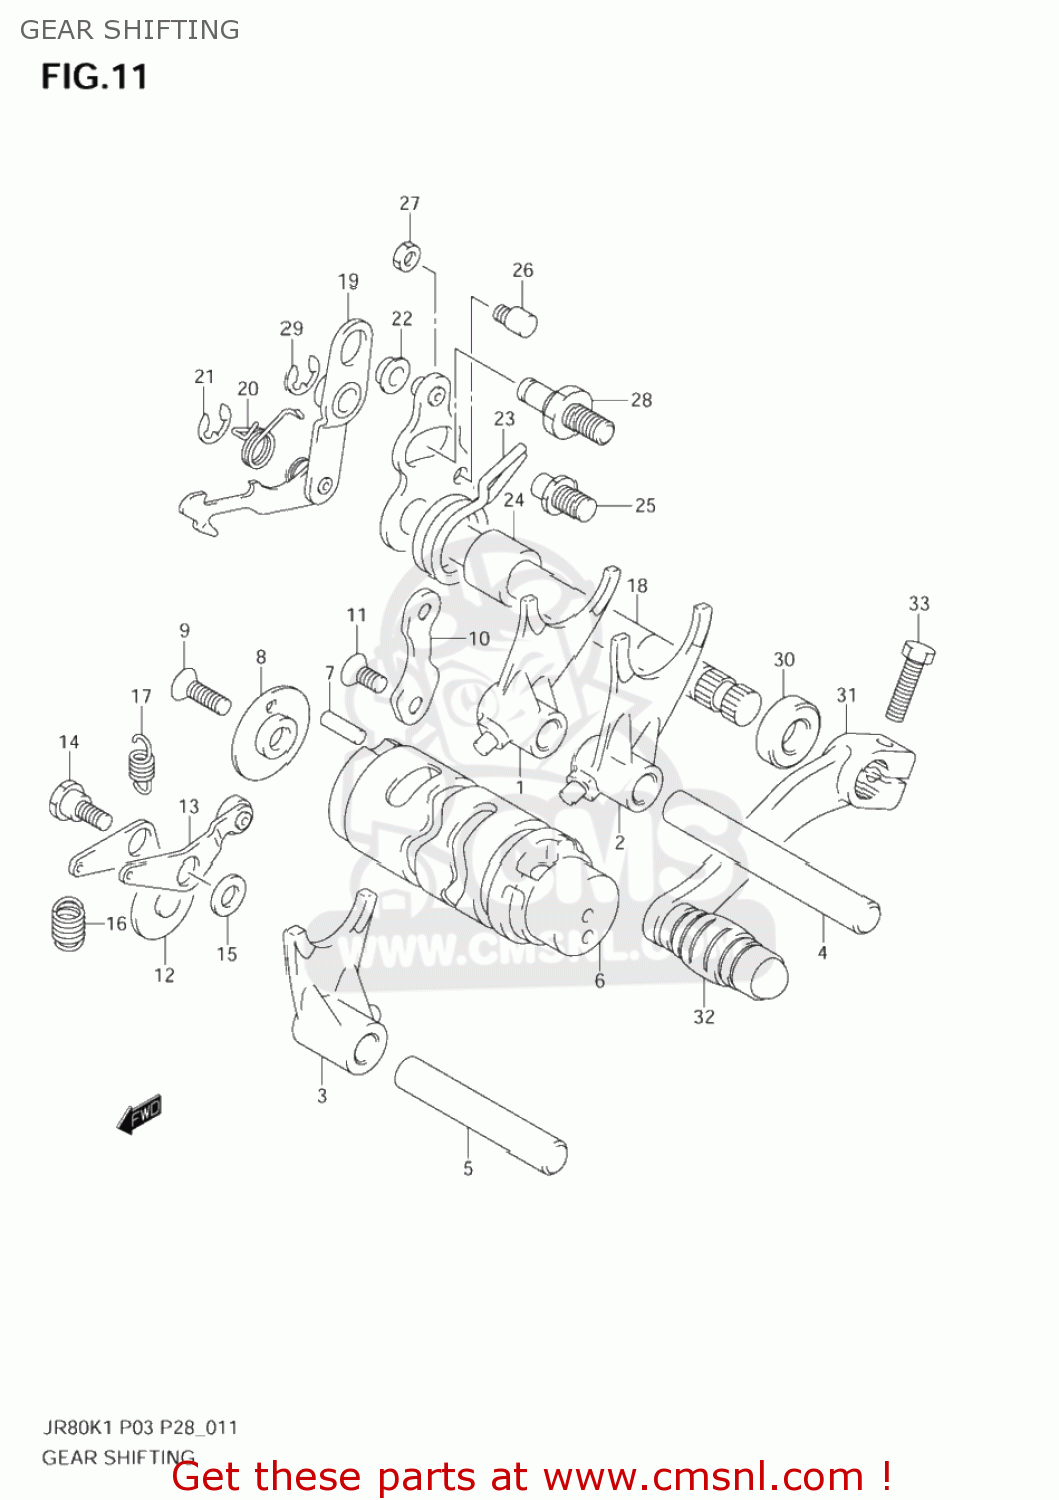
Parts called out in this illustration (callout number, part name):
1	FORK,GEAR SHIFT NO.1
2	FORK,GEAR SHIFT NO.2
3	FORK,GEAR SHIFT NO.2
4	SHAFT,GEAR SHIFT FORK
5	SHAFT,GEAR SHIFT FORK NO.2
6	CAM,GEAR SHIFT
7	PIN
8	RETAINER,GEAR SHIFT CAM DR PIN
9	SCREW
10	GUIDE,GEAR SHIFT CAM
11	SCREW
12	STOPPER,GEAR SHIFT CAM
13	STOPPER,GEAR SHIFT CAM NEUTRAL
14	BOLT(6X18.3)
15	WASHER
16	SPRING
17	SPRING
18	SHAFT,GEAR SHIFT
19	PAWL,GEAR SHIFT
20	SPRING
21	E-RING
22	SPACER(7X10X5)
23	SPRING
24	SPACER(12X20X15.3)
25	STOPPER,GEAR SHIFT ARM
26	BOLT,GEAR SHAFT RETURN SPR SET
27	NUT
28	STOPPER,GEAR SHIFT CAM
29	E.RING
30	OIL SEAL
31	LEVER ASSY,GEAR SHIFT
32	RUBBER,GEAR SHIFT PEDAL
33	BOLT
